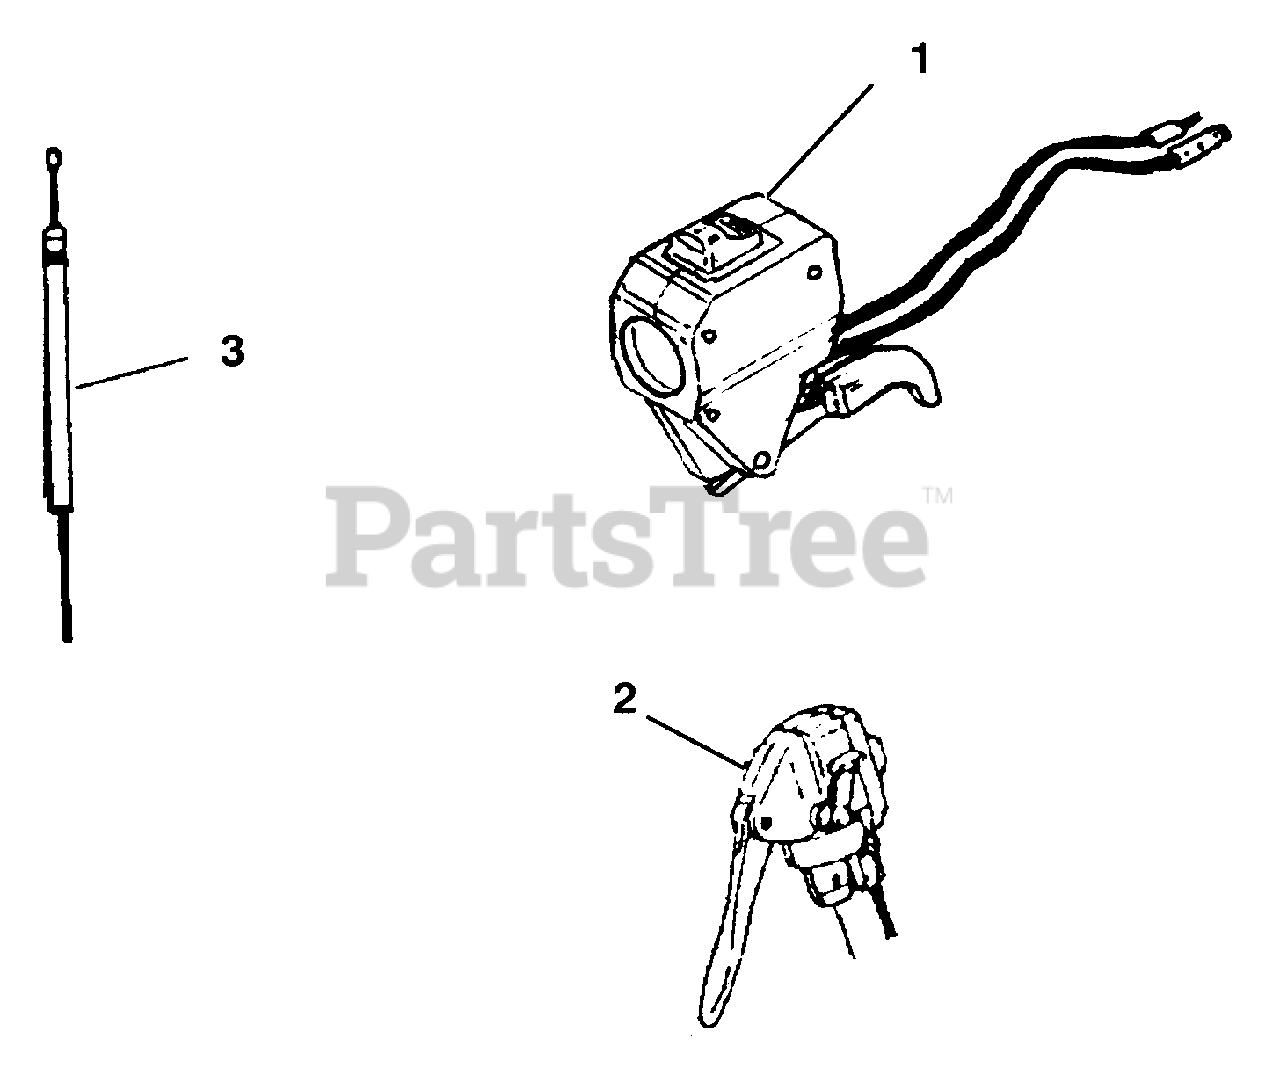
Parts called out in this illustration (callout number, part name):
1	Throttle Assembly
2	Throttle Switch Assembly
3	Throttle Cable
